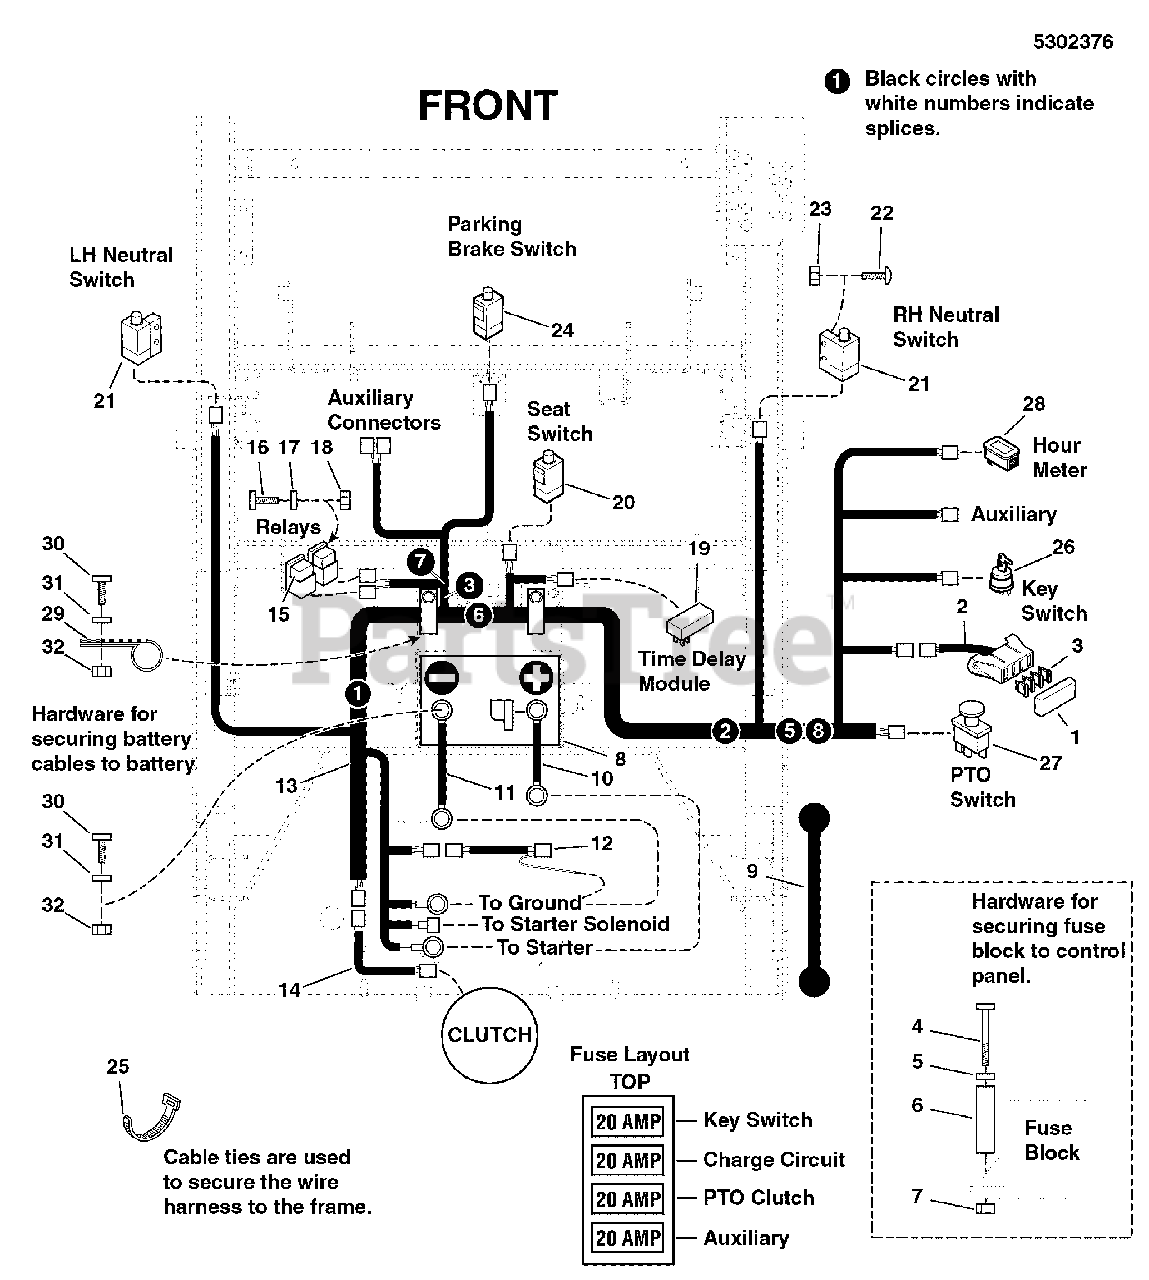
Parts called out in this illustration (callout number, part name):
1	COVER, VINYL FUSEBLOCK
2	WIRE HARNESS, FUSE BLOCK - IS2000
3	FUSE, ATO, 20 AMP (SV)
4	SCREW, #10-24 X 2 ROUND PHILLIPS
5	WASHER, #10 SAE
6	SPACER, .20 X .38 X 1.25
7	NUT, #10-24 HEX NYLON LOCK
8	BATTERY, WET (BCIU1, 340 CCA)
9	STRAP-BLACK RUBB
10	BATTERY CABLE, POSITIVE, 22
11	BATTERY CABLE, NEGATIVE, 14"
12	WIRE HARNESS, BIG BLOCK KAWI JUMPER
13	WIRE HARNESS, MAIN, S200XT
14	WIRE, HARNESS, JUMPER, WARNER CLUTCH
15	RELAY, 12V, 40A
16	BOLT, 1/4-20 X 3/4 GD5 YZ
17	WASHER, 1/4 SAE
18	NUT, 1/4-20 HEX SERR. FLANGE
19	MODULE, TIME DELAY
20	SWITCH, PLUNGER, NO/NO SNAP-IN
21	SWITCH, PLUNGER, N.O.
22	SCREW- #10-24 X 1/2 ROUND PHILLIPS
23	NUT, #10-24 HEX
24	SWITCH, DP NO/NC SNAP-IN
25	CABLE TIE, 12
26	SWITCH, IGNITION, 6 POST
27	SWITCH, BLADE ENGAGEMENT
28	HOUR METER
29	CLAMP, VINYL INSULATED
30	BOLT, 1/4-20 X 3/4 GD5 YZ
31	WASHER, 1/4 SAE
32	NUT, 1/4-20 HEX NYLOCK FLANGE
